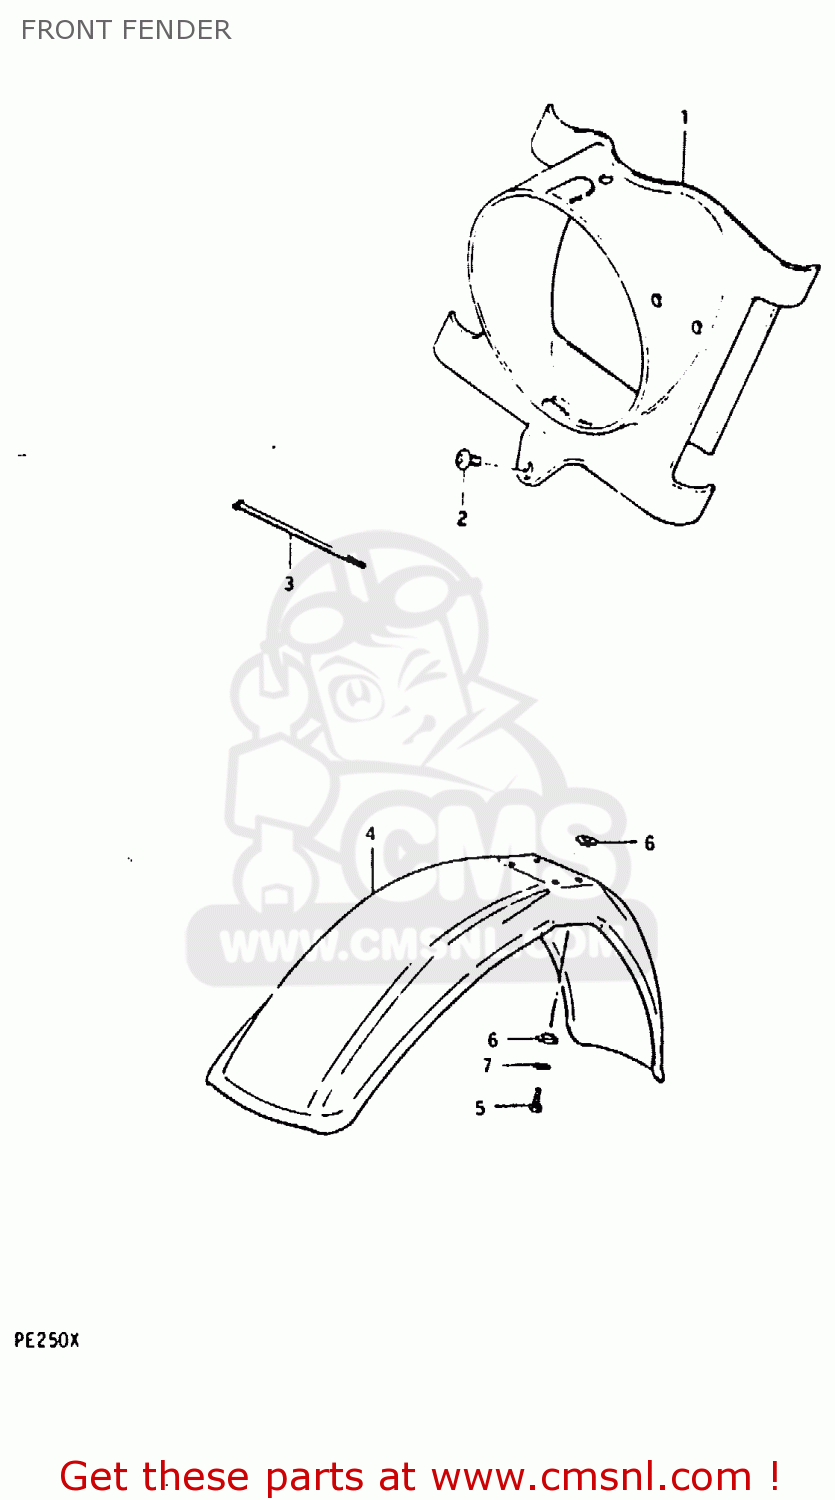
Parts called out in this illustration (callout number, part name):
1	HOUSING,HEADLAMP
2	SCREW
3	CLAMP
4	FENDER,FRONT
5	BOLT, UPPER
6	WASHER
7	LOCK WASHER
